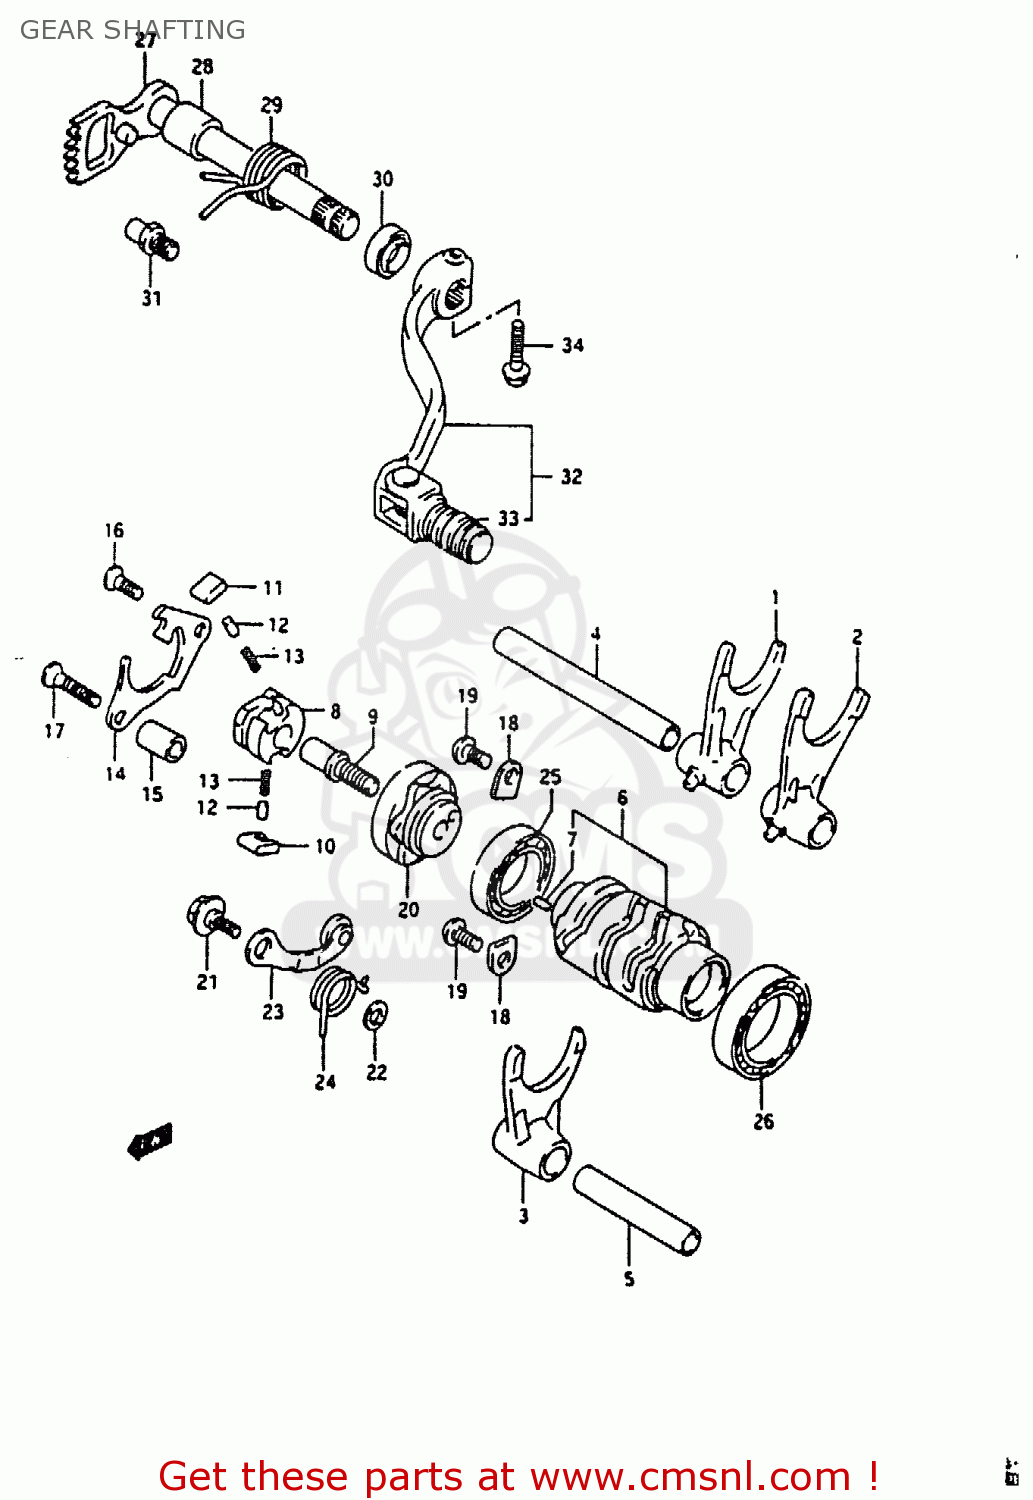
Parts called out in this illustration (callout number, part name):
1	FORK,GEAR SHIFT NO.1
2	FORK,GEAR SHIFT NO.2
3	FORK,GEAR SHIFT NO.3
4	SHAFT,GEAR SHIFT FORK
5	SHAFT,GEAR SHIFT FORK
6	CAM,GEAR SHIFT
7	PIN
8	GEAR,GEARSHIFT CAM DRIVE
9	PIN,SHIFT CAM DRIVEN GEAR
10	PAWL,GEAR SHIFT NO.1
11	PAWL,GEAR SHIFT NO.2
12	PIN(5X8)
13	SPRING
14	LIFTER,GEAR SHIFT POLE
15	SPACER(6.2X12X18)
16	SCREW
17	SCREW
18	RETAINER
19	SCREW
20	PLATE,GEAR SHIFT CAM STOPPER
21	BOLT(6X14.3)
22	WASHER
23	STOPPER,SHIFT CAM
24	SPRING
25	BEARING
26	BEARING(30X37X12)
27	SHAFT,GEAR SHIFT
28	SPACER(14X20X17.5)
29	SPRING
30	SEAL,OIL(14X22X6)
31	STOPPER,GEAR SHIFT CAM
32	LEVER ASSEMBLY,GEAR SHIFTING
33	RUBBER,GEAR SHIFT PEDAL
34	BOLT
